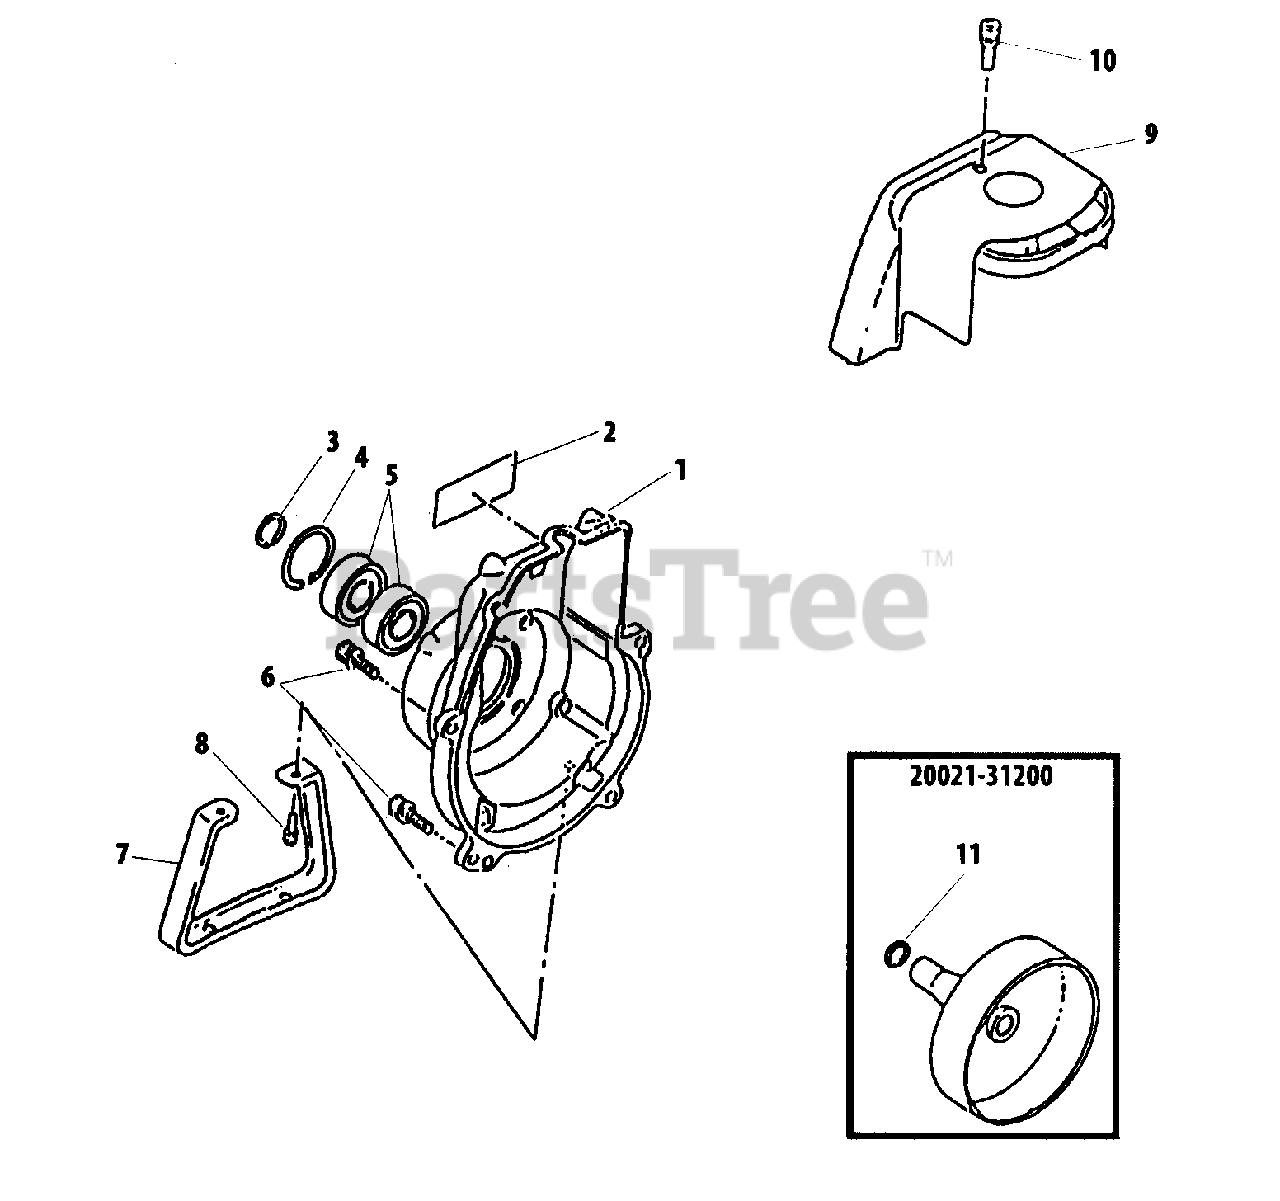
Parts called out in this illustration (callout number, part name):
1	COVER, FAN
2	LABEL, TRADE
3	RING, SNAP
4	RING, SNAP Ø32
5	BEARING, BALL 6002 DDU
6	BOLT M5×20
7	STAND
8	BOLT M5×16
9	COVER, ENGINE
10	BOLT 5×14
11	RING, SNAP Ø11.4
20021-31200	DRUM ASSY, CLUTCH
